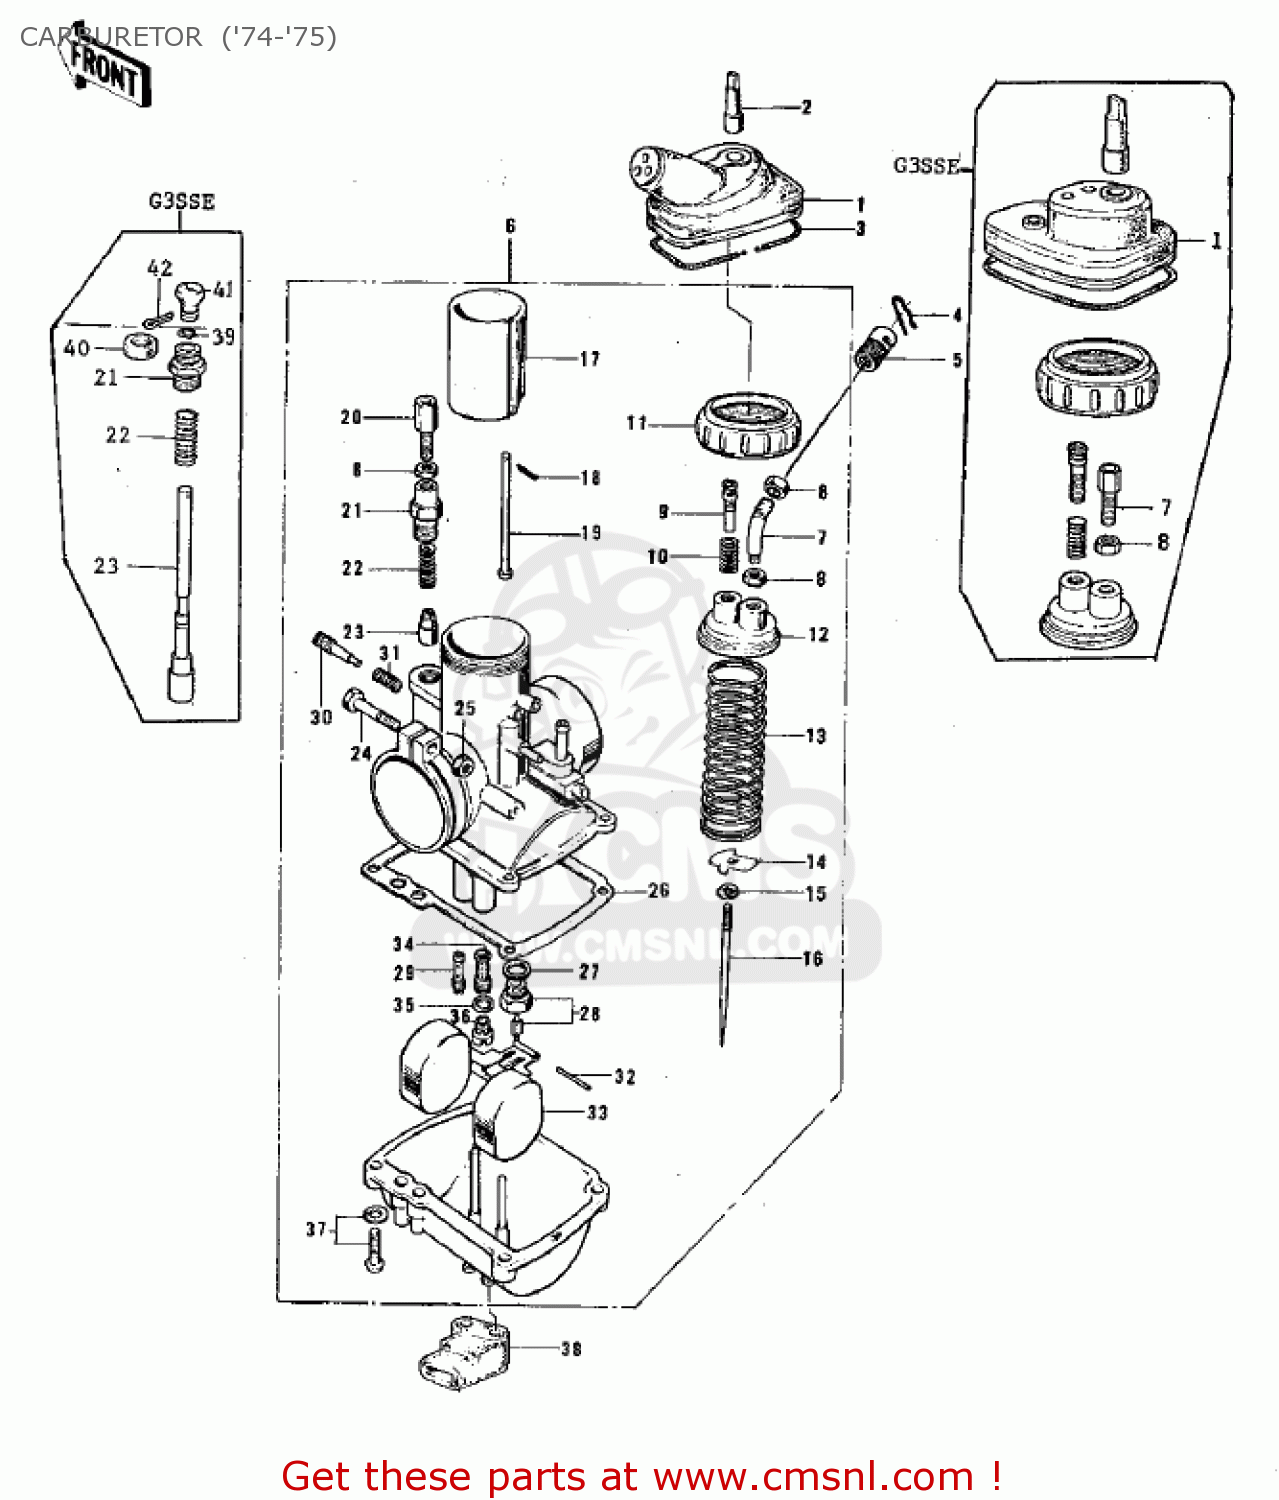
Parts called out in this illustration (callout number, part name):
1	BOOT,CARBURETOR
2	PLUG,12X40
3	SPRING,COIL
4	CIRCLIP
5	ADJUSTER-CABLE,THROTT
6	CARBURETOR ASSY
7	GUIDE,CABLE
8	NUT-CABLE ADJUST LOCK
9	THROTTLE STOP SCREW
10	SPRING-THR STOP SCREW
11	CAP-CHAMBER,MIXING
12	TOP-CHAMBER,MIXING
13	SPRING-THROTTLE VALVE
14	SEAT-SPRING,THROTTLE
15	CLAMP,E-TYPE
16	NEEDLE-JET,4EJ7
17	VALVE-THROTTLE,CA2.0
18	PIN-COTTER,1.2X10
19	ROD,THROTTLE VALVE ST
20	ADJUSTER-CABLE,STARTE
21	CAP-STARTER PLUNGER
22	SPRING-STARTER PLUNG
23	PLUNGER,STARTER
24	SCREW-CLAMP
25	NUT,6MM
26	GASKET,FLOAT CHAMBER (NAS)
27	WASHER-VALVE SEAT
28	VALVE-FLOAT,#2.0
29	JET-PILOT,#17.5
30	SCREW-PILOT AIR
31	SPRING-THR STOP SCREW
32	FLOAT PIN
33	FLOAT
34	JET-NEEDLE,O-2
35	WASHER-MAIN JET
36	JET-MAIN,#75R
38	GROMMET,OVERFLOW PIPE
39	CLAMP
40	BOOT,STARTER PLUNGER
41	KNOB,CARBURETOR
42	PIN-COTTER,1.6X15
